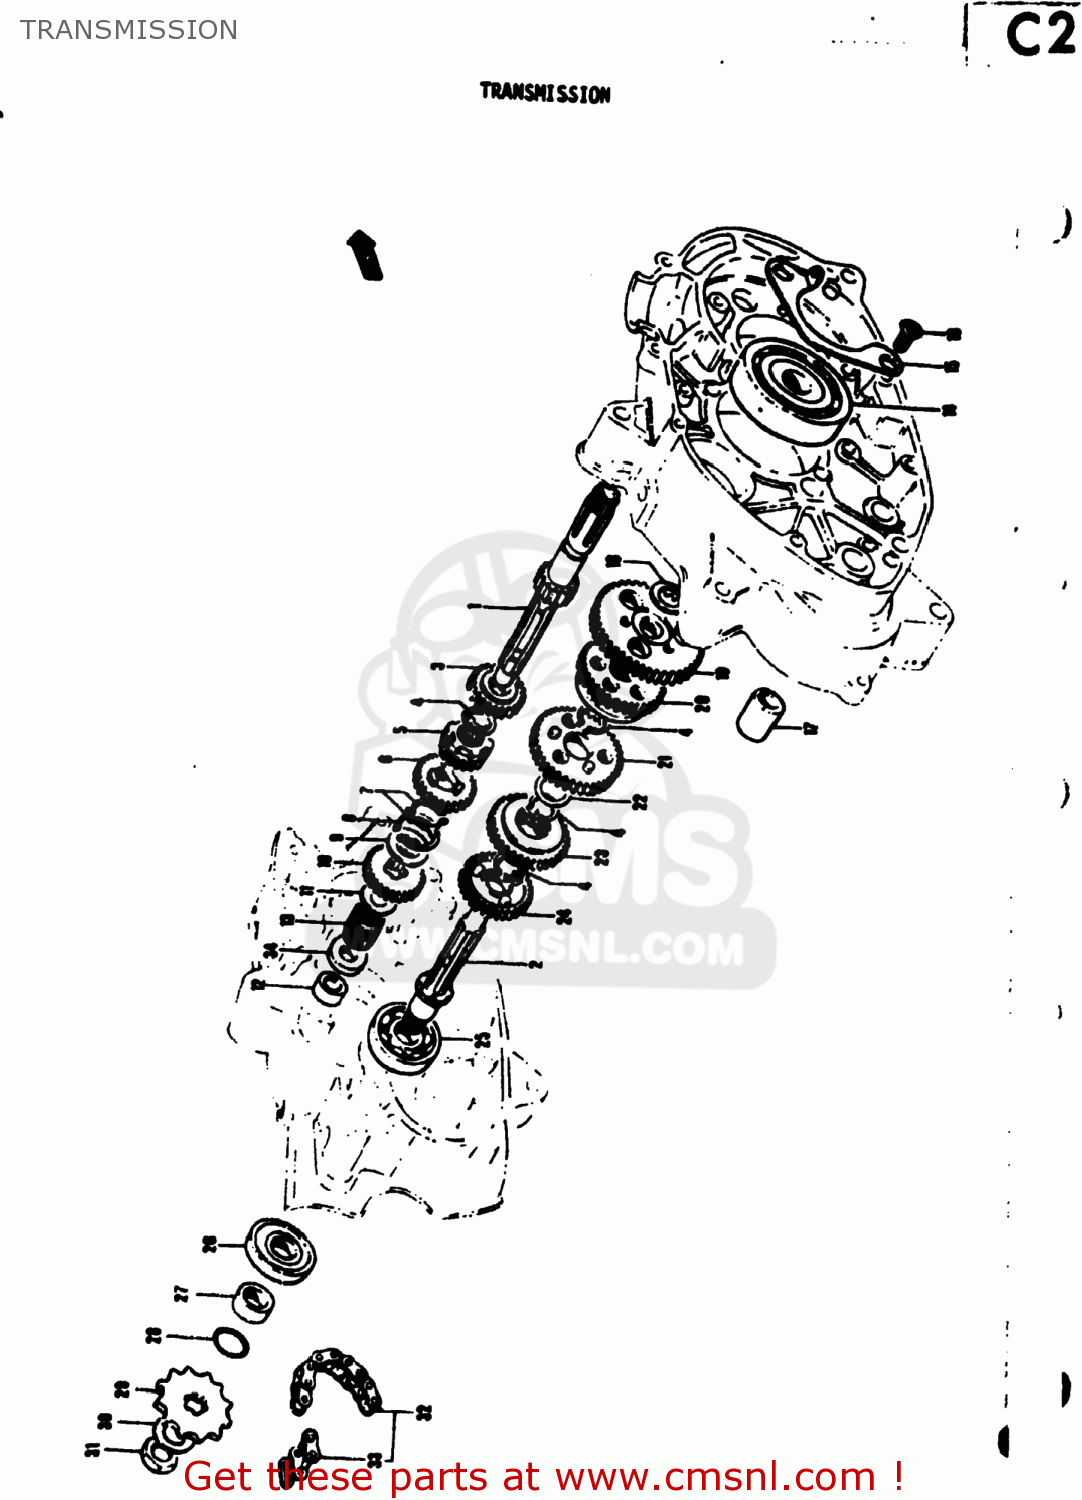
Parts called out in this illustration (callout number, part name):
1	SHAFT,COUNTER
2	SHAFT,DRIVE
3	GEAR,THIRD DRIVE
4	CIRCLIP
5	GEAR,SECOND DRIVE
6	GEAR,FOURTH DRIVE
7	RING
8	RING,SNAP
9	WASHER
10	GEAR,FIFTH DRIVE
11	WASHER
12	BUSH(12X19X11)
13	BEARING(12X19X12)
14	BEARING(17X62X10)
15	PLATE,COUNTERSHAFT BEARING
16	SCREW
17	BUSH(12X19X11)
18	WASHER(12X24X1.5)
19	GEAR,FIRST DRIVEN
20	GEAR,3RD DRIVEN
21	GEAR,2ND DRIVEN
22	WASHER,LOCK
23	GEAR,FOURTH DRIVEN
24	GEAR,FIFTH DRIVEN
25	BEARING
26	SEAL,OIL(21X40X7)
27	SPACER(17X21X13)
28	O RING(D:1,ID:16.8)
29	SPROCKET,ENGINE
30	WASHER,LOCK
31	NUT
32	CHAIN ASSEMBLY,DRIVE
33	JOINT ASSEMBLY,CHAIN
34	SEAL,OIL(5.5X16X8)
